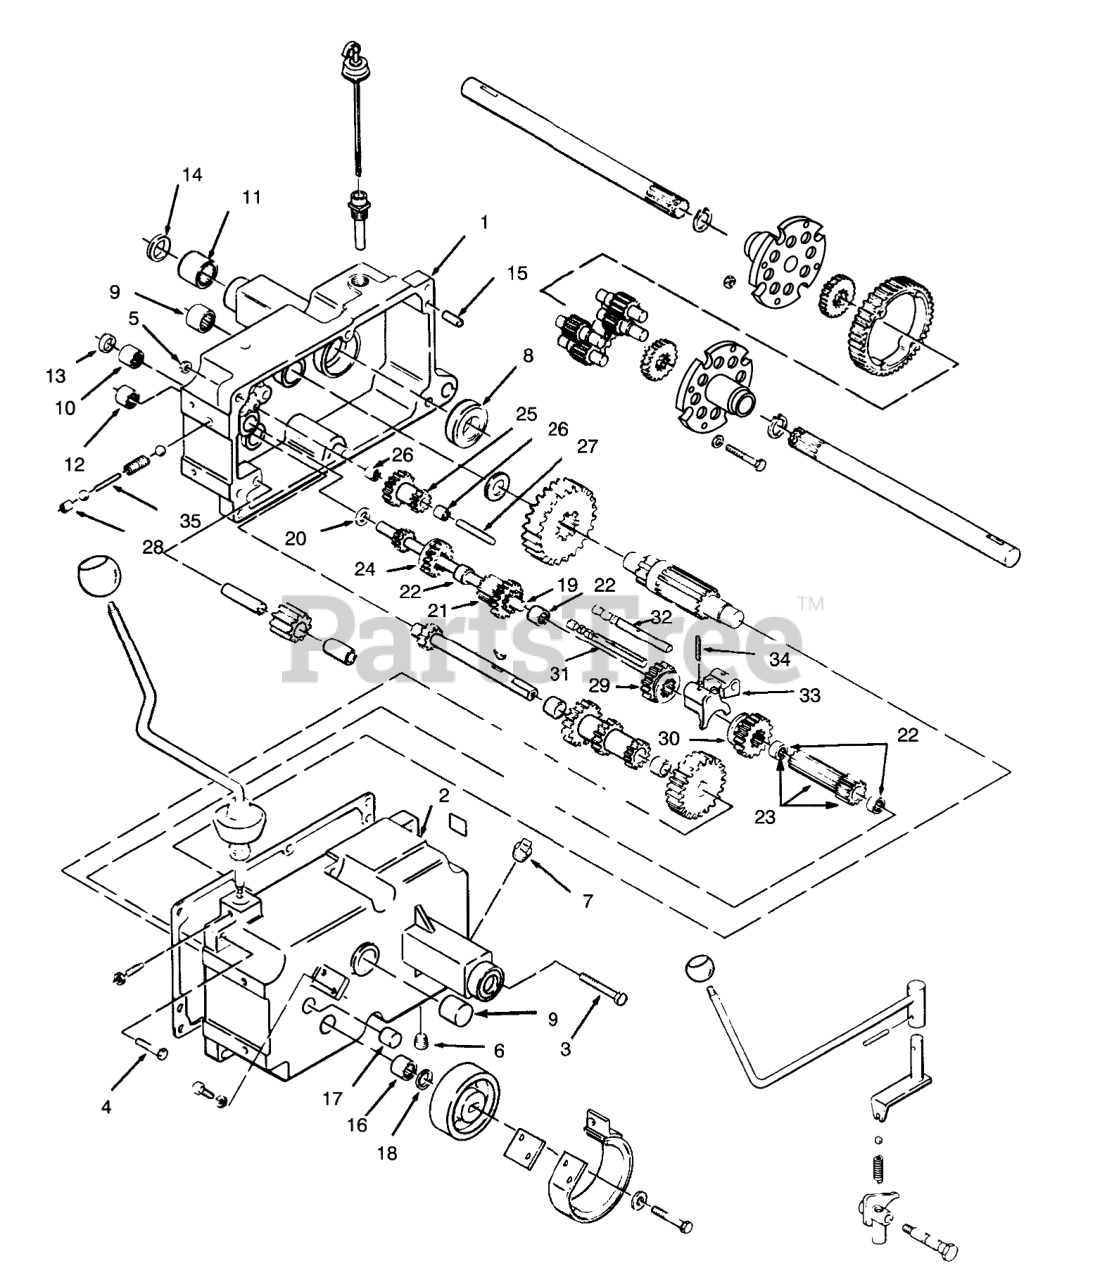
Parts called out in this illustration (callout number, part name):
1	Case Trans RH
2	Case Trans LH
3	SCREW-HH
4	SCREW-HH
5	NUT-LOCK, NI
7	PLUG-PIPE, SQH
8	BEARING-BALL
9	BEARING-NEEDLE
10	BEARING-NEEDLE
11	BEARING
12	BEARING-NEEDLE
13	SEAL-OIL
14	SEAL-OIL
15	PIN-DOWEL
16	BEARING-NEEDLE
17	BEARING-NEEDLE
18	SEAL-OIL
19	SHAFT-INPUT
20	WASHER-THR
21	Gear Assembly (Incl. Ref. #22)
22	BEARING-NEEDLE
23	Gear Assembly (Incl. Ref. #22)
24	GEAR-SLIDING
25	Gear
26	BEARING-NEEDLE
27	GEAR-SHAFT REDUCTION
28	CUP-PLUG
29	GEAR-HI AND 2ND
30	GEAR-LOW AND REVERSE
31	RAIL-SHIFT
32	RAIL-REAR SHIFT
33	FORK-SHIFT
34	PIN-ROLL
35	PIN-SHIFT
